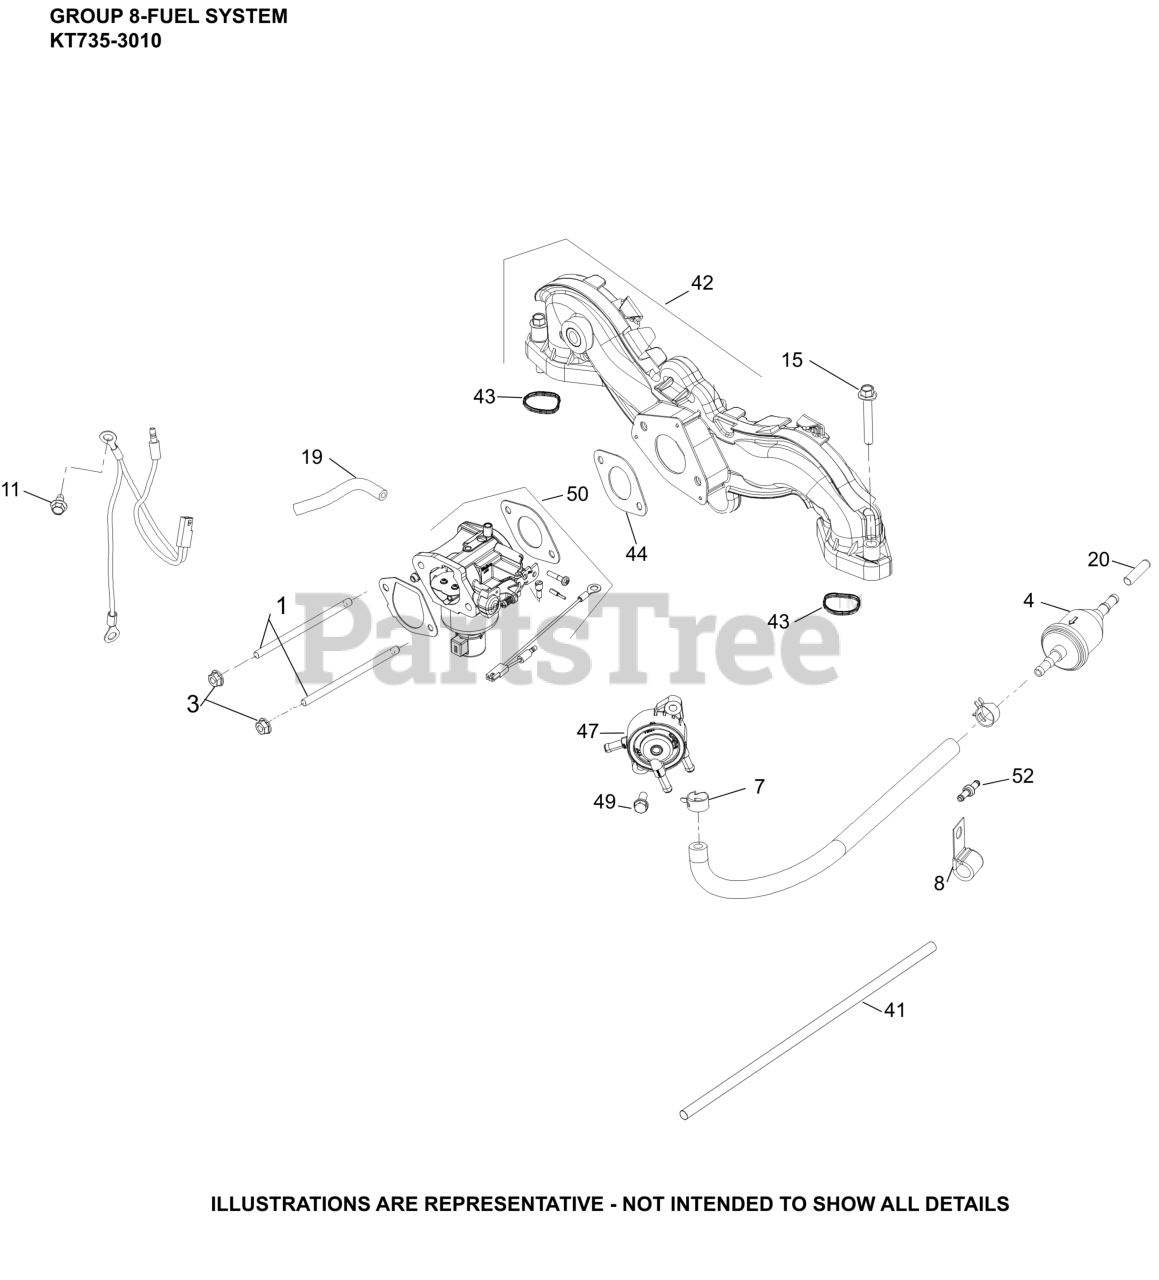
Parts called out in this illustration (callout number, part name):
3	NUT, FLG M6X1.0
4	FILTER,FUEL 51 MICRON (FUEL PUMP)
7	SPRING CLAMP, HOSE
8	CLIP, CABLE (KM)
11	SCREW, THREAD FORMING
15	SCREW, FLG M6X1.0X40
19	HOSE, EVAPORATIVE 20"- (#24326143S)
20	CAP, MASKING
41	SLEEVE, ANTI-ABRASION
42	INTAKE MANIFOLD W/GASKETS
43	O-RING, INTAKE PORT
44	GASKET, CARBURETOR (PIM, CV)
47	PUMP, FUEL (PULSE)
49	SCREW, HEX HEAD
50	KIT, CARBURETOR COMPLETE
52	FITTING, FUEL SYSTEM
NI	KIT,REPAIR OVERHAUL(WALBRO)
NI	KIT,BOWL O-RING(WALBRO)
NI	KIT, HIGH ALT (4000-8000 FT)WALBRO)
NI	KIT,SOLENOID REPAIR(WALBRO)
NI	KIT,REPAIR FLOAT(WALBRO)
